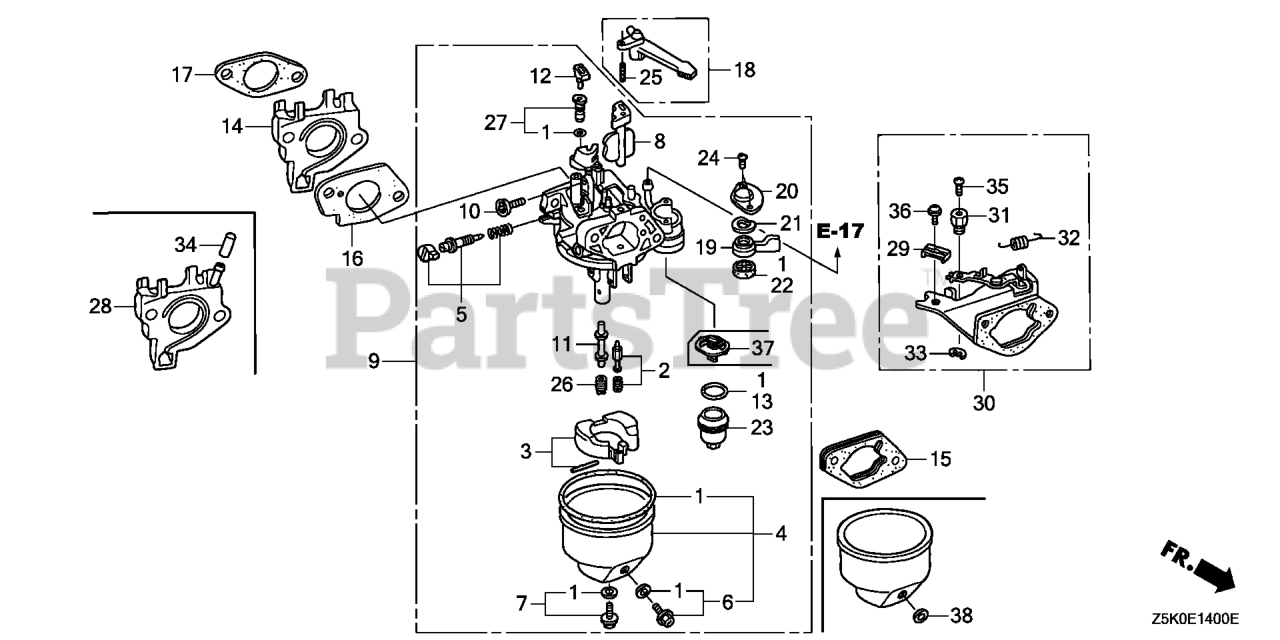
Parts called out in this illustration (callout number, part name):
1	GASKET SET (INCLUDE 16173-001-004) (INCLUDES 16173-001-004)
2	VALVE SET, FLOAT
3	FLOAT SET (CARBURETOR NO.)
4	CHAMBER SET, FLOAT
5	SCREW SET
5	SCREW SET (Honda Code 4219879). (CARBURETOR NO.)
6	SCREW SET, DRAIN
7	SCREW SET (CARBURETOR NO.)
8	CHOKE SET
9	CARBURETOR ASSY. (BE21J A)
9	CARBURETOR ASSY. (BE70U A)
10	SCREW, THROTTLE STOP
11	NOZZLE, MAIN
11	NOZZLE, MAIN (CARBURETOR NO.)
12	COLLAR, SET
13	GASKET, FUEL STRAINER CUP
14	INSULATOR, CARBURETOR
15	SPACER, CARBURETOR
16	GASKET, CARBURETOR
17	GASKET, INSULATOR
18	LEVER, CHOKE (STD)
19	LEVER, VALVE
20	PLATE, LEVER SETTING (CARBURETOR NO.)
21	SPRING, PETCOCK LEVER (CARBURETOR NO.)
22	GASKET, VALVE
23	CUP, FUEL STRAINER
24	SCREW, PAN (3X6)
25	PIN, SPRING (2X12)
26	JET, MAIN (#82)
26	JET, MAIN (#85) Use up to Engine SN BE81B B.
26	JET, MAIN (#88) Use up to Engine SN BE81B B.
27	JET SET, PILOT (#35)
27	JET SET, PILOT (#38)
37	FILTER, CUP (CARBURETOR NO.)
38	WASHER, PLAIN (6.2X10.7 DRAIN) (CARBURETOR NO.)
